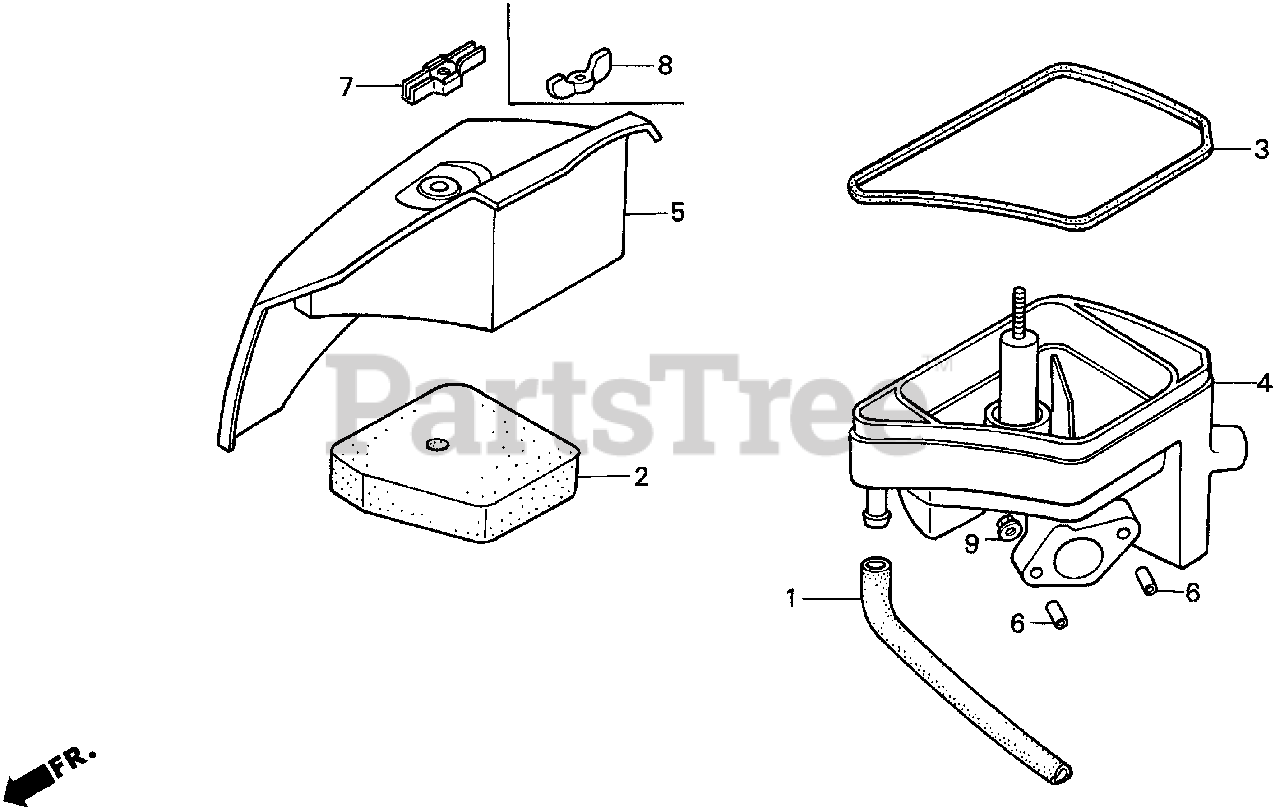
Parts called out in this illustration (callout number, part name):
1	TUBE, BREATHER
2	ELEMENT, AIR CLEANER
3	RUBBER, SEAL
4	HOUSING, AIR CLEANER
5	COVER, AIR CLEANER *R8* (BRIGHT RED)
6	COLLAR, AIR CLEANER HOUSING
7	WINGNUT, AIR CLEANER COVER
7	WINGNUT (6MM)
8	WINGNUT, TOOL BOX SETTING
9	NUT, FLANGE (5MM)
